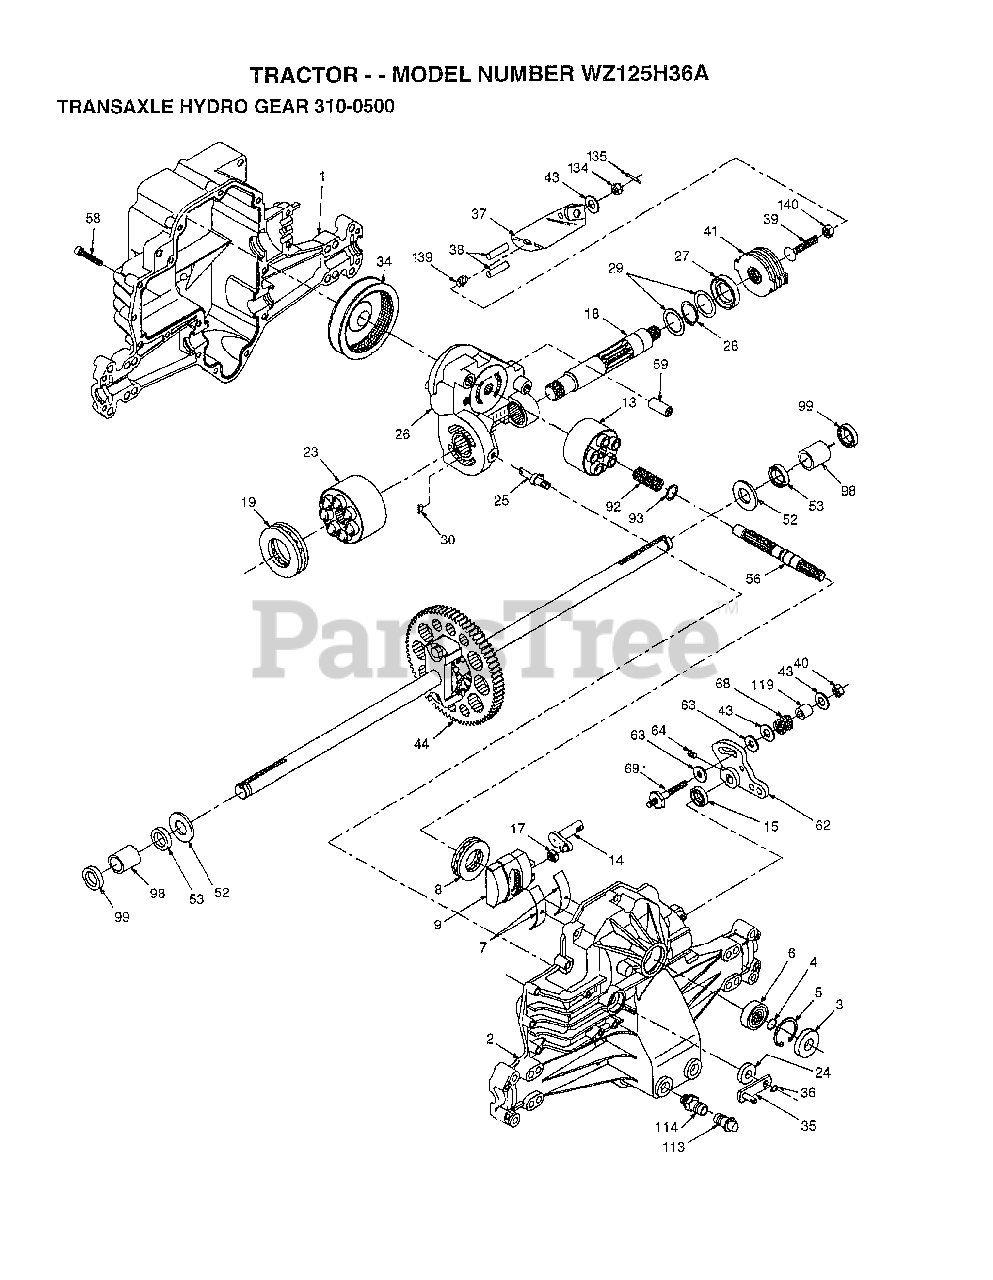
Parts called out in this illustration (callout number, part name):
1	HOUSING.L.44863RM
2	ASSEMBLY UPPER HOUSIN
3	SEAL.9008000-0128
4	RING.RET.2003016.
5	RING.RET.2003052.
6	BEARING.(50552)42X68X16
7	CRADLE- 2003023.
8	BEARING.THU.50551
9	SWASHPLT.2003087.
13	BLOCK.CLYN.70079.
14	ARM.TRUN.2003005.
15	SEAL.9008000-0126
17	GUIDE.2000015.
18	SHAFT.MOTOR.50449
19	BEARING.THU.50552
23	BLOCK.CYLIN.70082
24	SEAL.LIP.45074
25	ACTUATOR.2003555
26	KIT.CEN.SEC.70250
27	SEAL.LIP.45075
28	RING RETAIN 50007
29	WASHER.44872
34	ELEMENT.OIL.44964
35	ARM.BYPASS.50270
36	RING.RETAIN.44870
37	ARM.ACTUAT.23710
38	PIN.ACTUAT.44891
39	BOLT.50316
40	NUT.LOCK.HX.50317
41	KIT.BRAKE.70135
43	WASHER HYD 44130
52	DIFFERNTIAL.70126
52	WASHER.HYD.44875
53	SEAL.HYDRO.45076
56	SHAFT.INPUT.50005
58	BOLT.1/4-20.44876
59	PIN.HYDRO.50002
62	ARM.CONTROL.50254
62	SPRING.2003014.
63	PUCK.DAMPER.50281
64	SCREW.SET.50018.
68	SPRING.HYD.50277
69	STUD.5/16-24.DANA
93	WASHER.2003017
98	BEARING.SLV.50137
99	SEAL.WIPER.50941
113	CAP.VENT.70109
114	O-RING.ASM.70110
119	SPACER.HYD.50278
134	NUT.CAS.HYD.44142
135	PIN.COT.HYD.44101
139	SPRING.COMP.50431
140	NUT.HEX.50269
